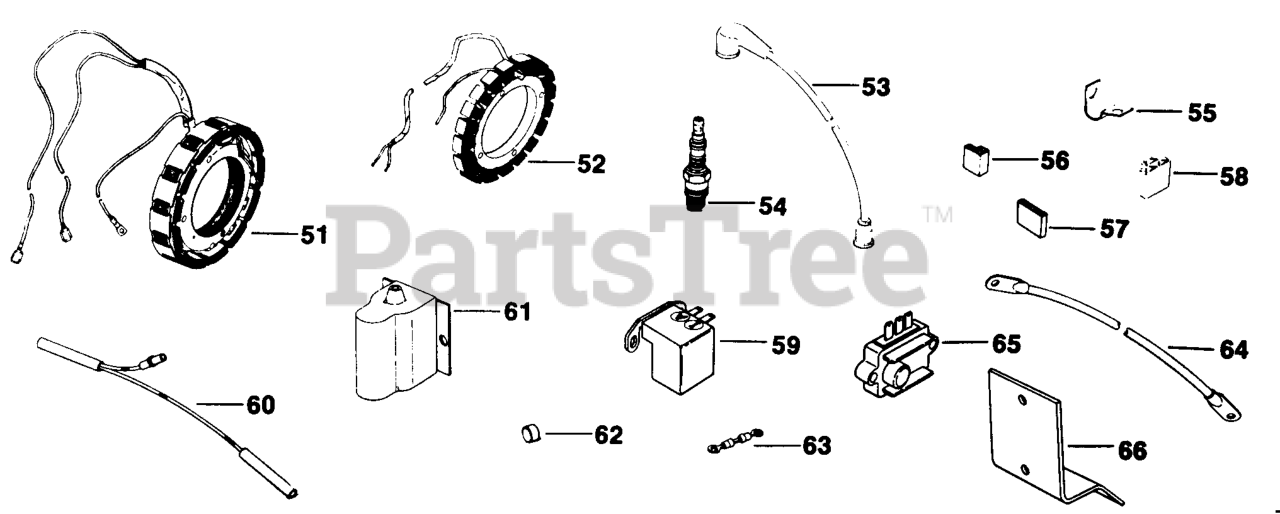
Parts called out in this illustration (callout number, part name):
51	KIT, STATOR - DISCONTINUED
53	KIT, HI-TENSION-(#DSC)
54	SPARK PLUG USE 25 132 10-S
57	CONNECTOR, BODY (KM)-USE 25 155 41-S
59	TRIGGER - DISCONTINUED
60	TRIGGER LEAD - DISCONTINUED
62	PLUG, CUP 3/16" USE 25 139 51-S
65	REGULATOR
